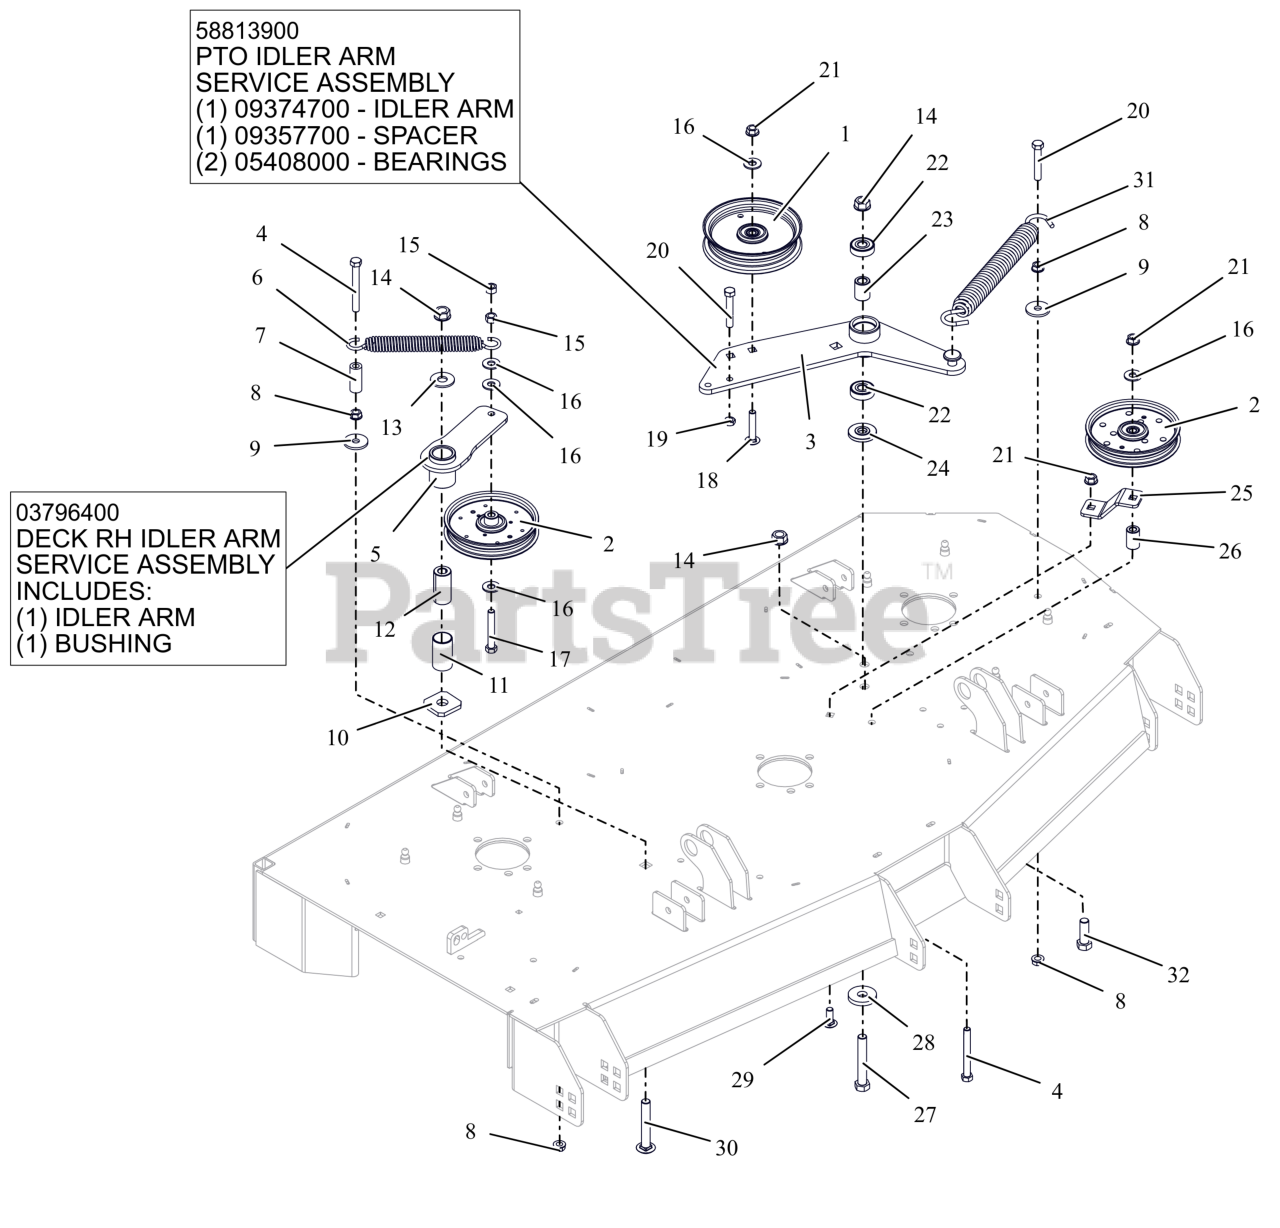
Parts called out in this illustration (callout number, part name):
1	IDLER- FLAT - 5.00" X .75"
2	IDLER- 5" FLANGED
3	WLDMT, IDLER ARM PT660
3	PTO IDLER ARM
3	SPACER .510 X .867 X 1.1485
3	BRG-BALL .500X1.38X.437
4	BLT, HEX .38-16X3.25 G5 ZCC
5	WMT, IDLER ARM - BLACK
5	ASM, IDLER ARM (DECK)
6	SPRING- EXTENSION
7	HOSE, .38 X 1.65
8	NUT, SPNLK-FLG .38-16 G5 ZCC
9	WSHR,FLT .406X1.375X.135 ZCC
10	WSHR-FLT .640X1.75X.250
11	BSHG, 1.00X1.125X1.937
12	BSHG, SPCR .502X.997X2.03 PM
13	WSHR,FLT .563X1.375X.109 ZCC
14	NUT-LK-CTR-FLG .500-13 GG ZCC
15	NUT-LK-CTR .38-16 ZC120
16	WSHR,FLT .438X1.00X.083 ZCC
17	BLT, HEX .38-16X2.50 G5 ZCC
18	BLT,RHSSN.375-16X2.00 G5 ZCC
19	NUT-JAM .375-16 G2 ZCC
20	BLT,HEX .38-16X2.25 G5 ZCC
21	NUT-LK-CTR-FLG .375-16 GF ZCC
22	BRG-BALL .500X1.38X.437
23	SPACER .510 X .867 X 1.1485
24	SPACER, IDLER ARM
25	PTO FIXED IDLER MTG BRKT -RED
26	BUSHING, SLV .380X.750X1.190
27	BLT,HEX .50-13X3.25 G5 ZCC
28	WSHR-FL-STL 0.557X1.625X0.25 ZCC
29	BLT,RHSSN .38-16X1.00 G5 ZCC
30	BTL,RHSSN .500-13 X 3.25 G5 ZCC
31	SPRING, EXTENSION
32	BLT,HEX .50-13X1.50 G5 ZCC
